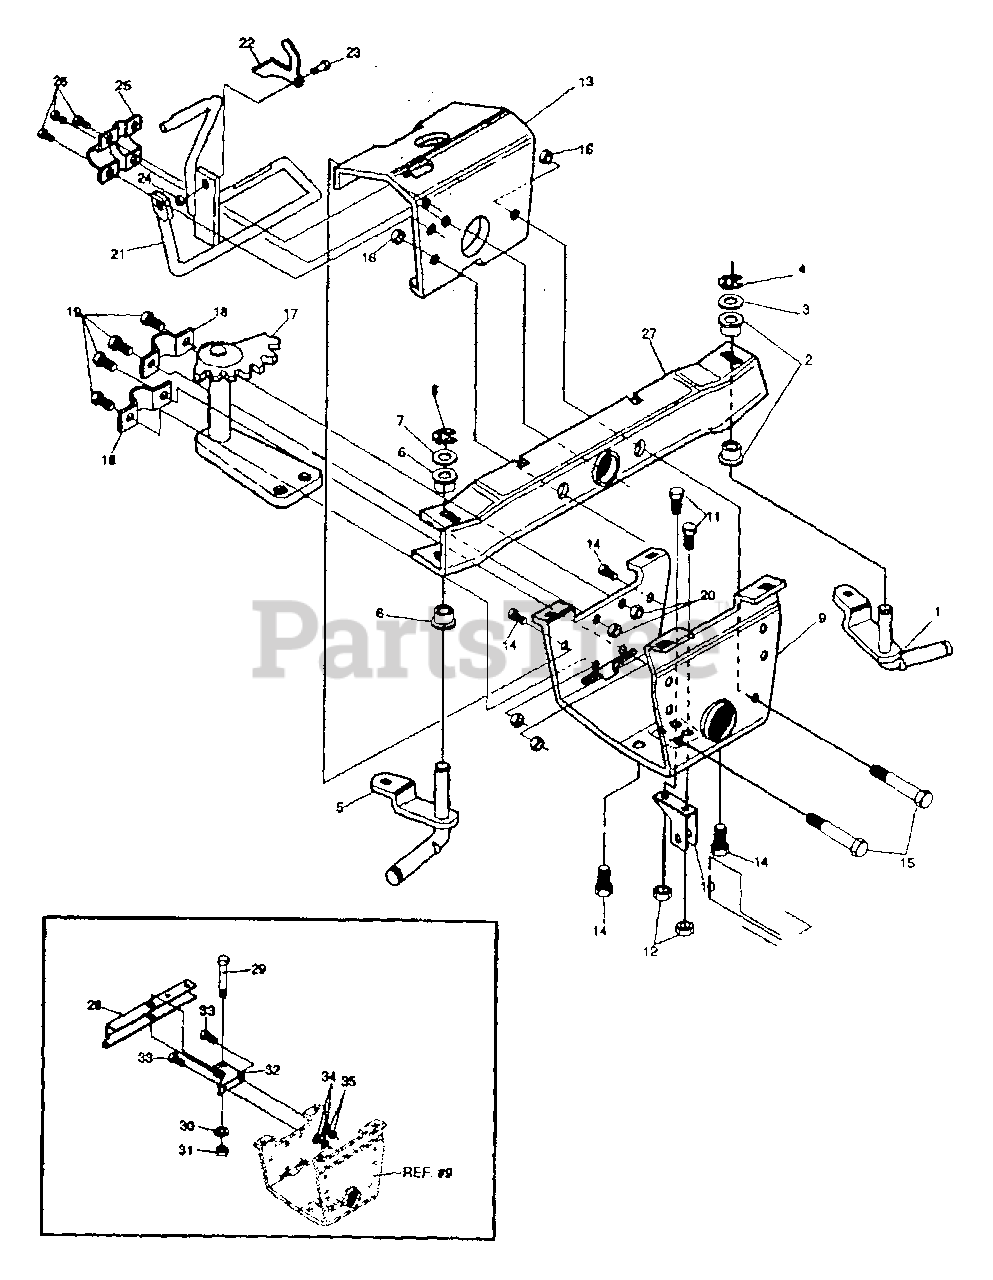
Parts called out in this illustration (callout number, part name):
1	Assembly Spindle L.H.
2	Bushing, Spindle
3	Washer, Flat.035 x 1.31 x .07
4	Ring, Ret E..48 x .04 TRU 5133-62
5	Assembly Spindle, R.N.
6	Bushing, Spindle
7	Washer, Flat.635 x 1.31 x .07
8	Ring, Retaining E .48 x .04TRU 5133-62
9	Bracket. Axle, Outer Front
11	Screw, 5/16-18 x.63 HHC GR2
12	Nut, 5/16-18 Reg H Ctr Lk
13	Axle Bracket, Inner
14	Screw, 5/18-18 x .50 WAHH Tap
15	Screw, 3/8-18 x 2.75 H HC GR 2
16	Nut, 3/8-16 Reg HX Clr Lk
17	Steering Assembly
18	Clamp, .625 Dia.
19	Screw, 5/16-18 a .63 H HC GR2
20	Nut, 5/16-18 Reg Hex CO Lk
21	Brake Arm Assembly
22	Latch, Parking Brake
23	Bolt, .373 x .140 H H SH 1/4-20
24	Nut, 1/4-20 Reg H Ctr Lk
25	Bracket, Clutch and Brake
26	Screw, 5/16-18 x.50 WA H H Tap
27	Front Axle Assembly
28	Rocker Arm Mower Engagement
29	Bolt 500 x 1.18 HHC 3/8-16
30	Washer,Flat .390 x 1.25 x .119
31	Nut, 38-16 REGHXCTRLK
33	Screw, 5/16-18x.63 HHC GRD 2
34	Washer, Flat .344 x .69 x .065
35	Nut, 5/16-18 REGHXCTRLK
